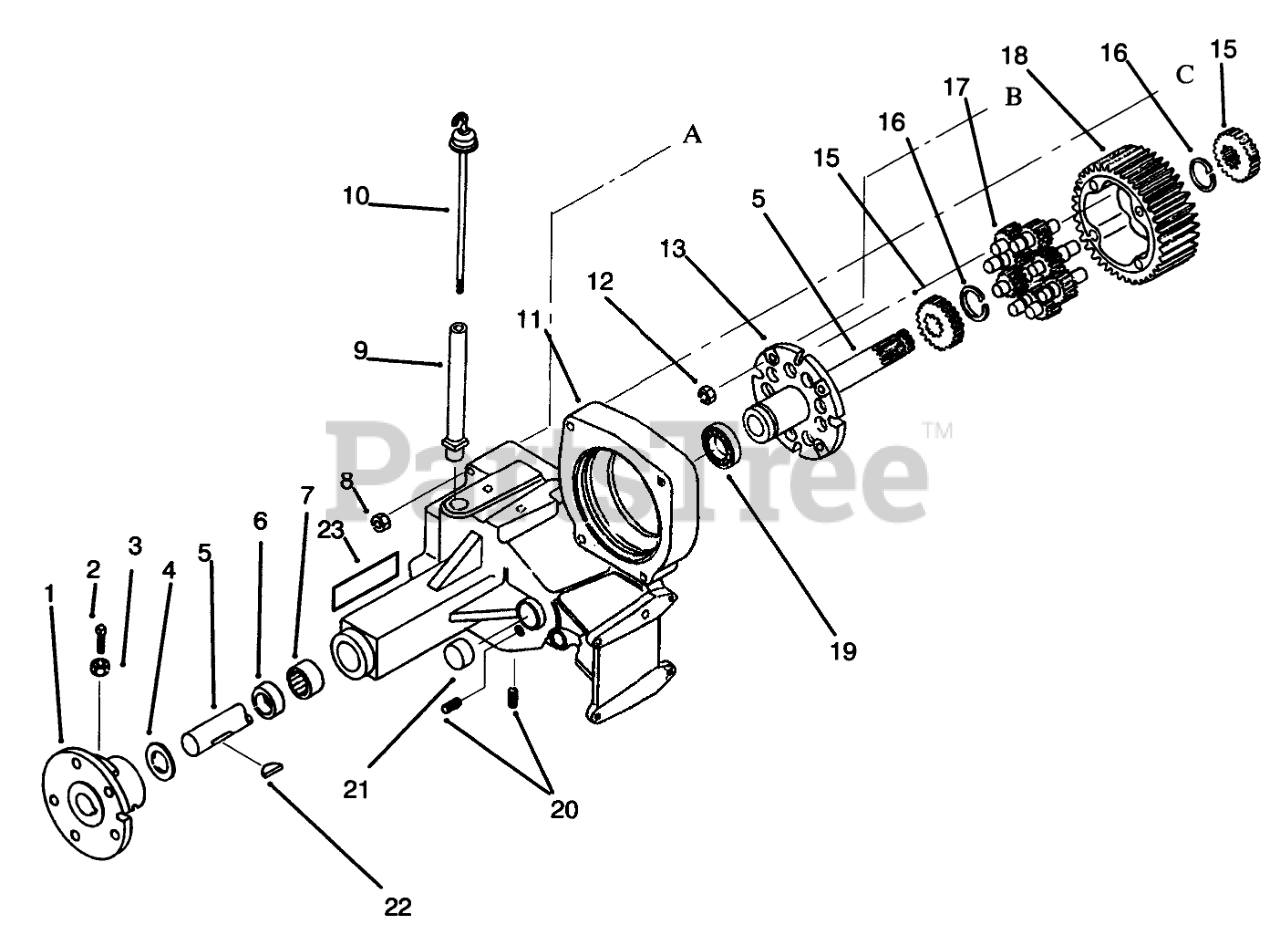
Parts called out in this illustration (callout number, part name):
1	Hub Rear
2	SCREW-SET, SQH
3	NUT-JAM
4	WASHER-THRUST
5	AXLE-REAR RH
6	SEAL-OIL
7	BEARING
8	NUT-LOCK, NI
9	NIPPLE-TRANS FILL
10	Dipstick
11	Case-Transaxle, RH (Incl. Ref. #23)
12	NUT
13	END CAP-DIFFERENTIAL
15	GEAR-AXLE DIFFERENTIAL
16	RING-SNAP
17	GEAR-PINION, 11T
18	GEAR-DIFFERENTIAL RING, 43T
19	BEARING-BALL
20	PLUG
21	BEARING-NEEDLE
22	KEY-WOODRUFF
23	DECAL - DANGER
